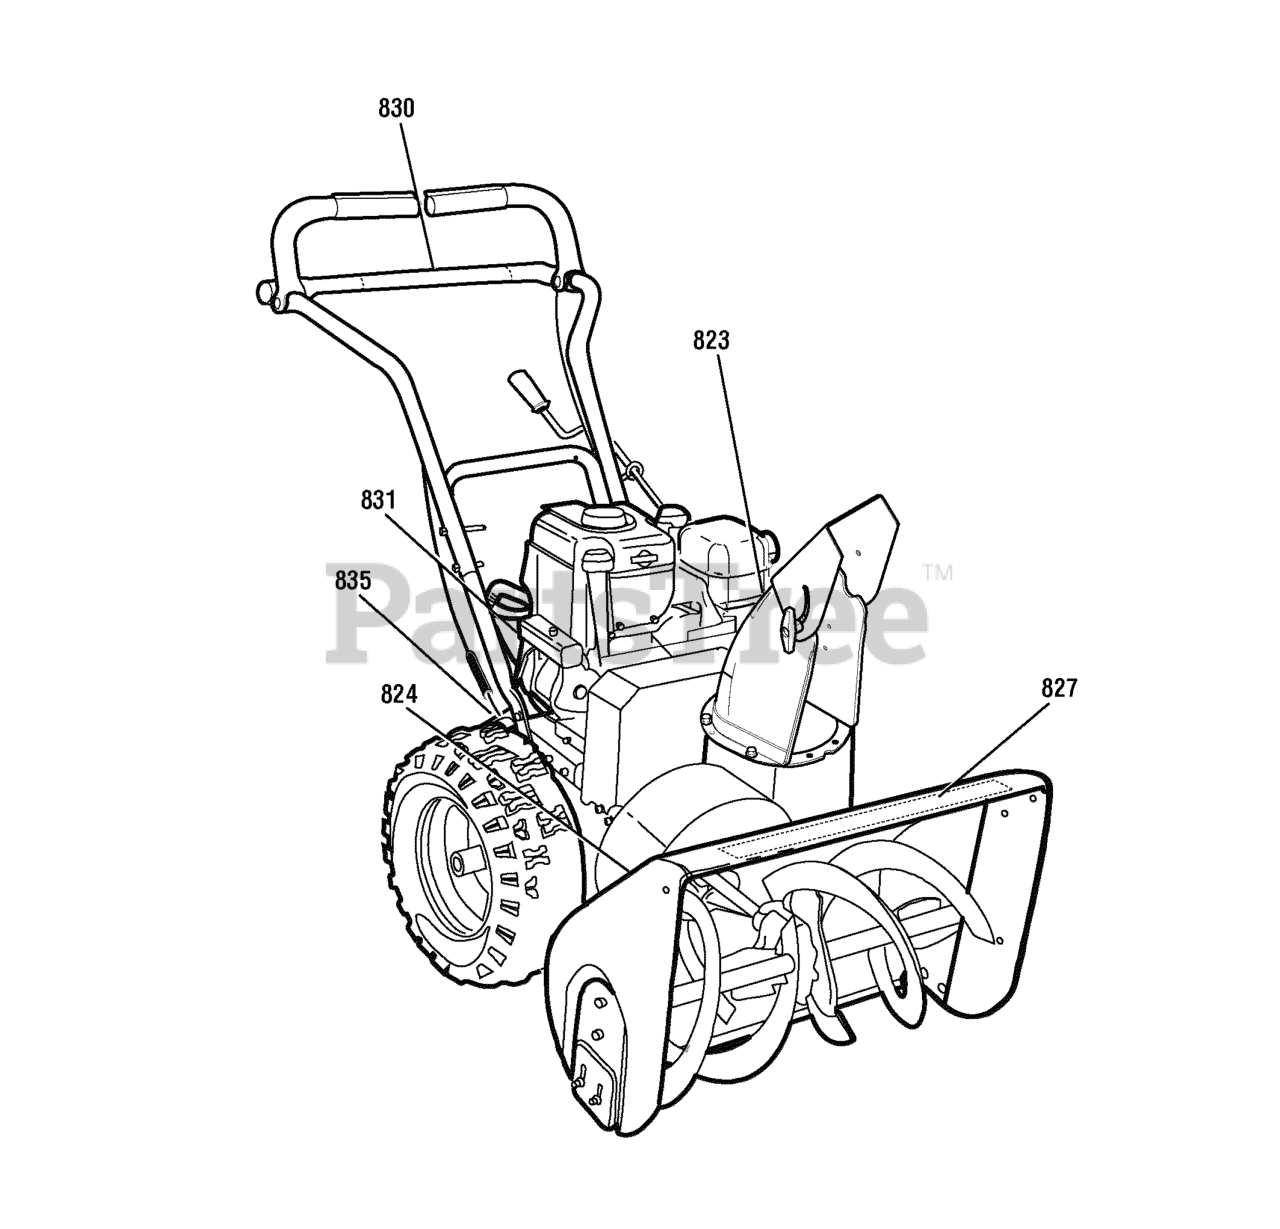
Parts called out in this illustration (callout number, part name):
823	DECAL, DANGER CHUTE HAND
824	DECAL, DANGER FOOT
827	DECAL, 900/24 CRAFTSMAN AUGER
830	DECAL, Controls, Gear Shift
831	DECAL, 1-6 Transmission Speed Control
835	DECAL, ID PLATE
